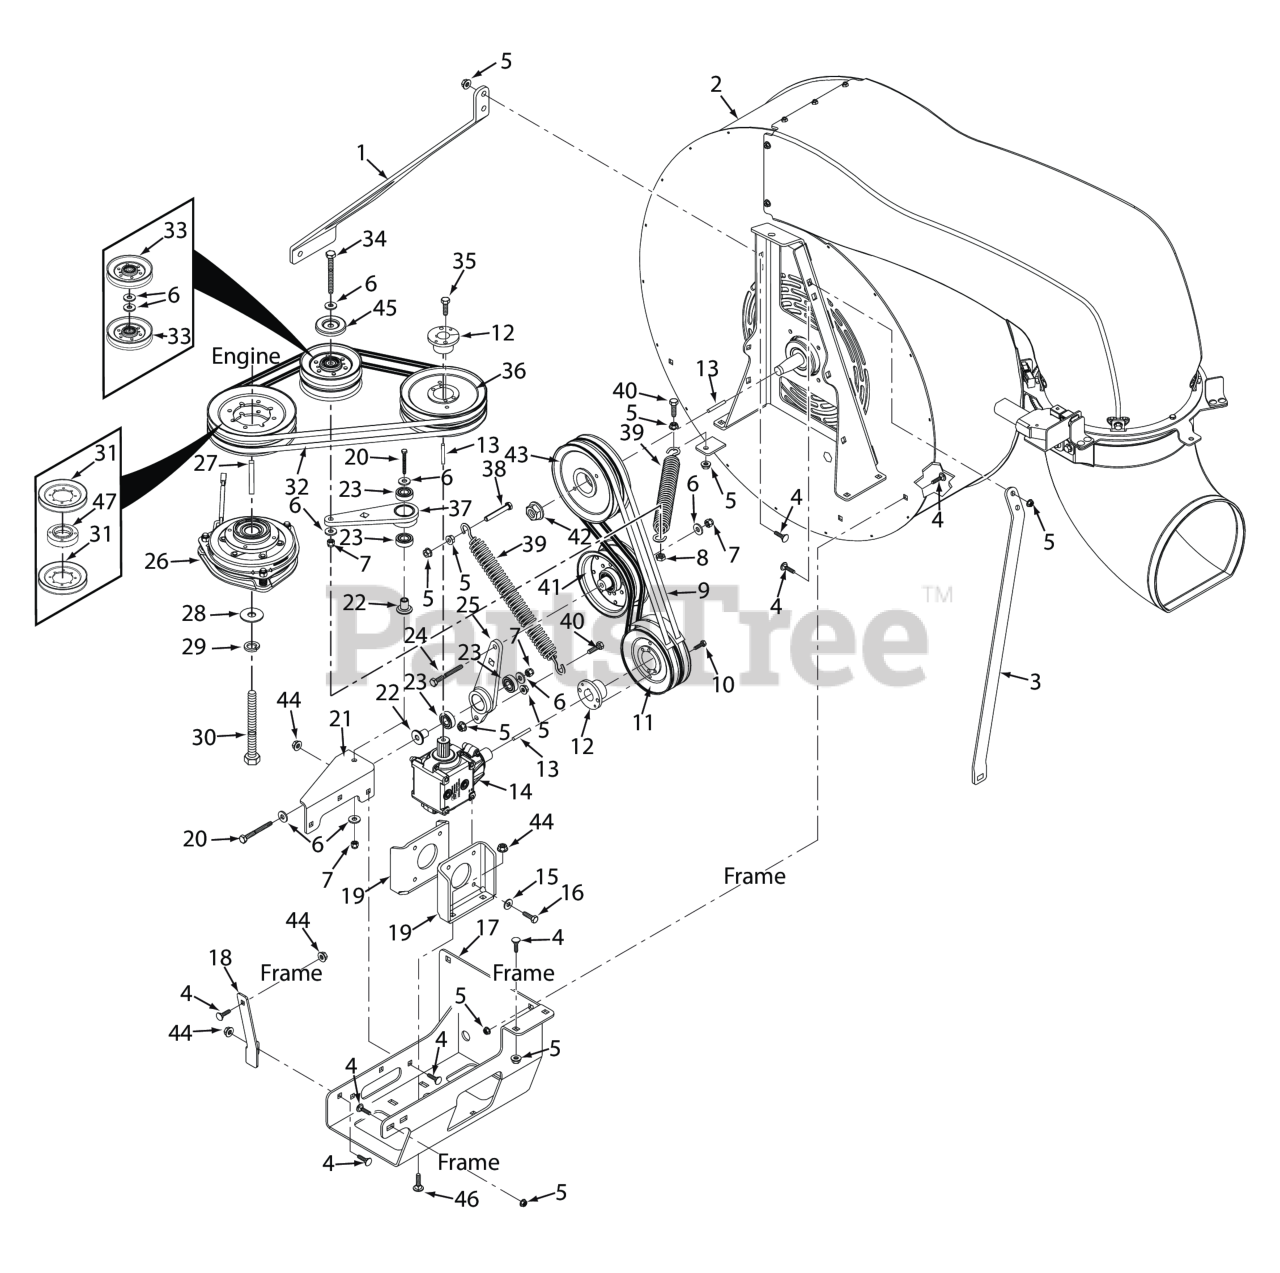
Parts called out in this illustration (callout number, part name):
1	LH Support Bar, Blower
2	Blower Housing, With Decal
3	RH Support Bar, Blower
4	Carriage Bolt, 3/8-16 x 1.0"
5	NUT, 3/8-16 SERRATED FLANGE HEX HEAD
6	Flatwasher, 3/8 (.391 x .938 x .105 HD) Grade 8
7	HEX NUT, ELASTIC STOP LOCK, 3/8-16
8	Bolt, Hex Head 3/8-16 x 1" Ser. Flg.
9	C-Belt, Gearbox Output
10	Hub, Tapered, 1" Bore
11	Pulley, Double Groove
12	TAPERED HUB, 1.00" BORE
13	Key, 1/4 x 1/4 x 1.25" Pulley Mtg.
14	Gearbox Assembly
15	Lockwasher, 5/16 (.317 x .586 x .078) Helical Spring
16	Bolt, Heax Head 5/16-18 x 1" (48V / 52V)
17	Mounting Bracket, Gearbox
18	Support Strap, Gearbox
19	Mounting Plate, Gearbox
20	Bolt, Hex Head 3/8-16 x 2-1/4" - 61"
21	Idler Arm Bracket, Gearbox
22	Pivot, Idler Short
23	BEARINGS, BALL, NEUTRAL RETURN
24	Bolt, Hex Head 3/8-16 x 3" - 52"
25	Idler Arm Assembly, Gearbox Output (INCL. 23)
26	Clutch, GT3.5 (28.6mm Bore)
27	Key, 1/4 x 1/4 x 3-1/2"
28	Flatwasher, 7/16-.469 x 1.75 x .25 (48, 52)
29	Lockwasher, 7/16� Spring
30	Bolt, Hex Head 7/16-20 x 3" w/t Patch
31	Pulley, Clutch 7.30 DIA
32	Belt, Gearbox Input
33	IDLER PULLEY, "V" GROOVE
34	Capscrew, Hex Head 3/8-16 x 3-3/4"
35	Bolt, Hex Head 1/4-20 x 1" Grade 8 Black
36	Pulley, Gearbox Input, 6.95 DIA, Double Groove
37	Idler Arm Assembly, Gearbox Input (INCL. 23)
38	Bolt, Hex Head 3/8-16 x 2-1/2" Grade 8
39	Spring, Transmission Drive
40	Bolt, Hex Head 3/8-16 x 1-1/2" Grade 8 Black
41	Pulley, Idler 5" Dia.
42	Nut, 3/4-16 Spriral Lock
43	Pulley, Blower, 6.95 DIA, Double Groove
44	Nut, Flange Elastic Stop Nut, 3/8-16
45	Quick Pin, 5/16" Dia.
46	Bolt, Carriage 3/8-16 x 1"
47	Hub, Clutch Pulley
